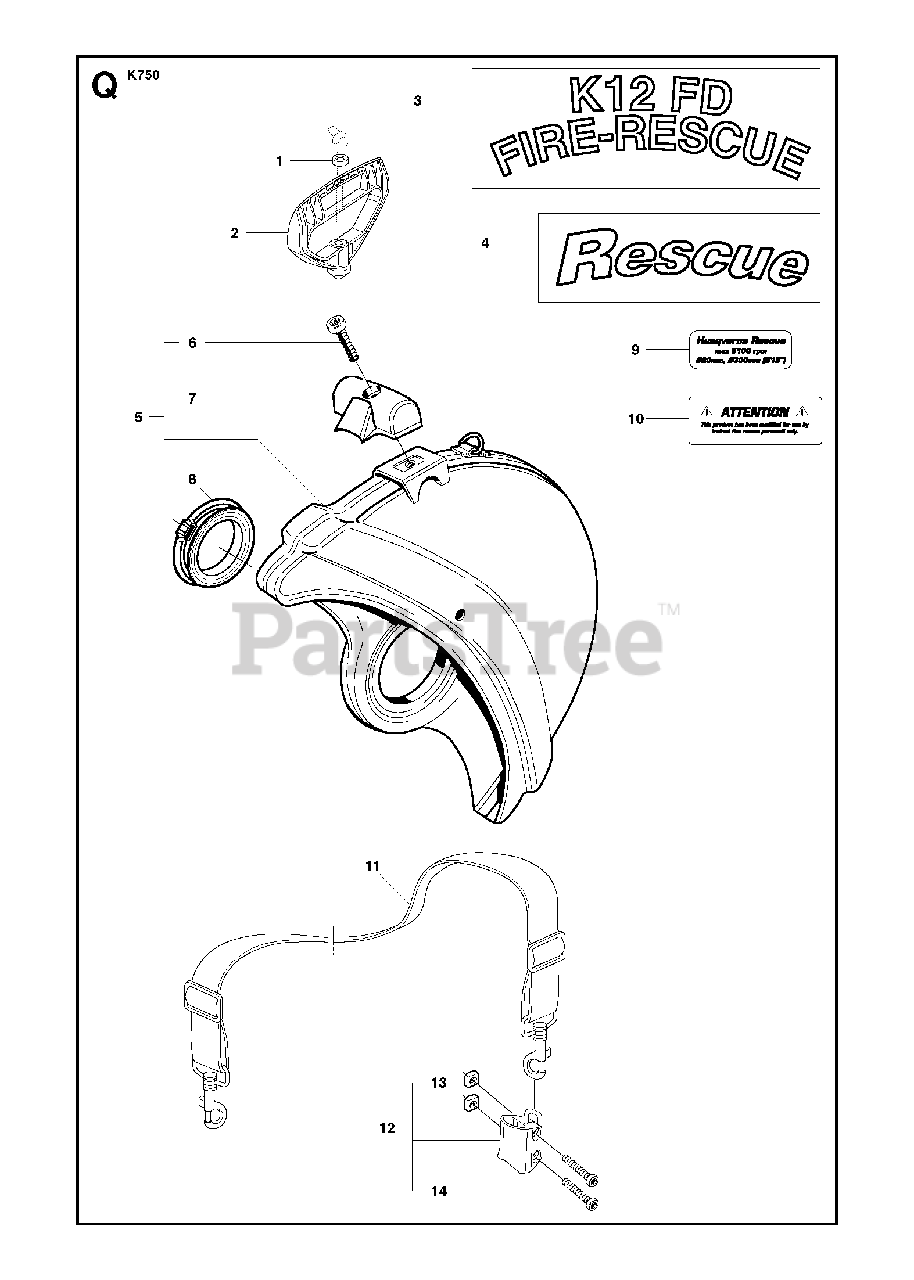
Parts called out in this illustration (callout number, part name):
2	STARTER HANDLE
5	BLADE GUARD"Rescue 12"". Incl. 6 - 8"
6	SCREW ITXSCM
11	SHOULDER STRAP
12	BRACKETIncl. 13, 14
14	SCREW ITXSCM
